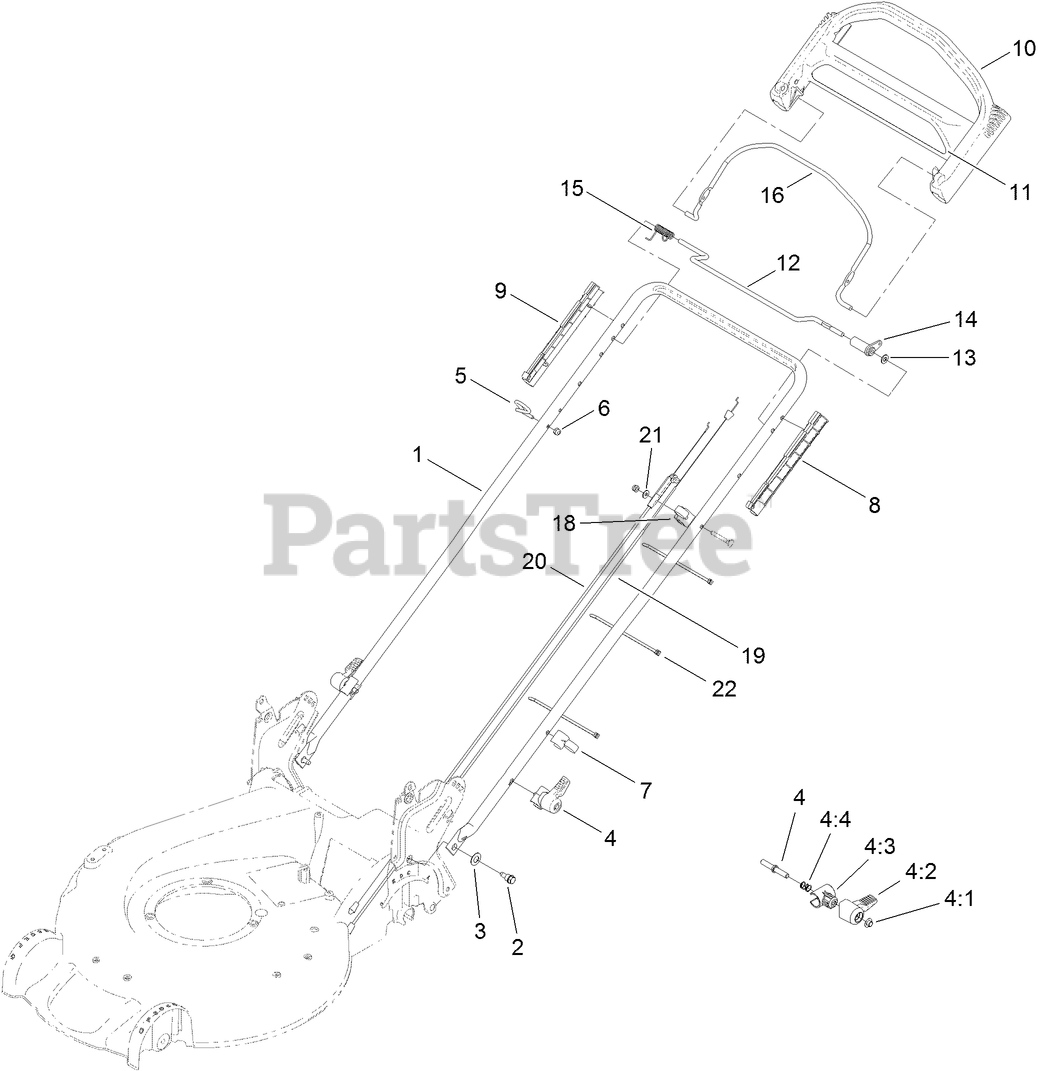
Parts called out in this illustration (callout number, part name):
2	BOLT-SHOULDER
3	WASHER-SPRING, CONICAL
4	QUICK RELEASE ASM
4:2	LEVER
4:3	ANCHOR-SPRING
4:4	SPRING-COMPRESSION
5	GUIDE-ROPE
6	NUT-LOCK, NI
7	GUIDE-CABLE
8	GUIDE-LH
9	GUIDE-RH
10	HANDLE-CONTROL
13	WASHER-PLAIN
14	LEVER-TRACTION
19	CABLE-TRACTION
20	CABLE-BRAKE
21	WASHER-FLAT
22	TIE-CABLE
